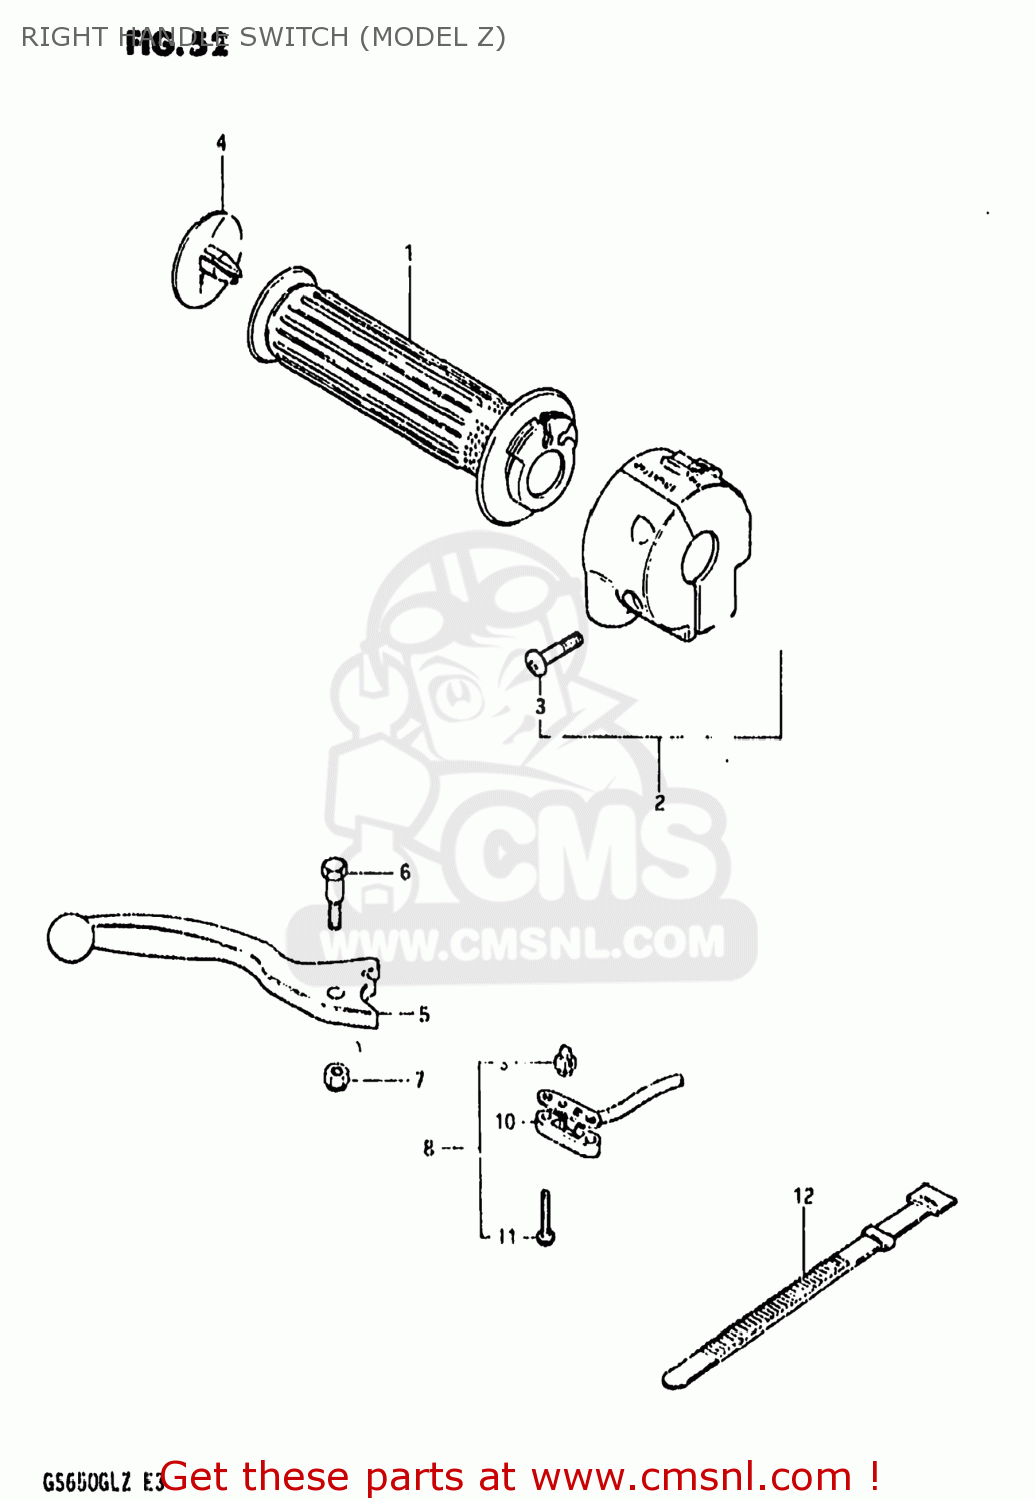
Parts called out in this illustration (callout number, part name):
1	GRIP,THROTTLE
2	SWITCH ASSEMBLY,HANDLE,RIGHT
3	SCREW
4	CAP,GRIP END
5	LEVER,BRAKE
6	BOLT
7	NUT 6MM
8	SWITCH ASSEMBLY
9	CONTACT,SWITCH
10	COVER,FR BK TERMINAL BASE
11	SCREW
12	CLAMP(L:120)
